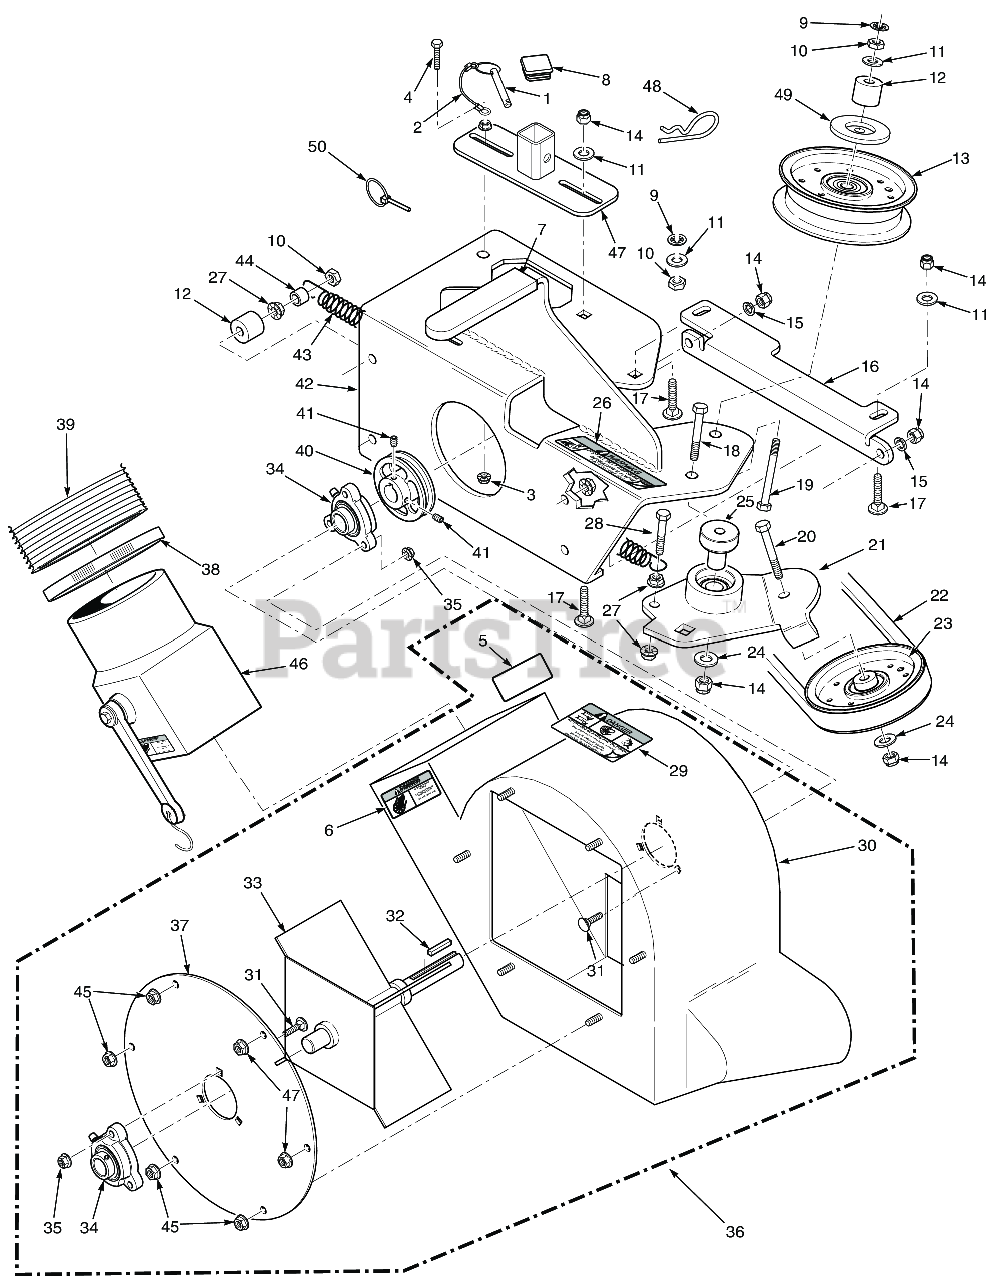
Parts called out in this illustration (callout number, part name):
1	Pin, Ring 1/2 x 2-1/4"
2	Lanyard, Deck Height Pin
3	NUT, 1/4-20 SERRATED FLANGE HEX HEAD
4	SERR. FLG. HEX HEAD CAPSCREW, 5/16-18 X 3/4
5	Decal, Blower
6	Decal, Rotating Blower
7	Grip, Deck Latch Lever
8	Cap, Square Vinyl
9	Nut, Push-On - 3/8" Dia.
10	Bolt, Hex Head 3/8-16 x 1" Ser. Flg.
11	Flatwasher, 3/8" Special (.391 x .938 x .105)
12	SPACER, J-PULL ROD
13	Pulley, Idler 3-1/2" Dia. - 52"
14	HEX NUT, ELASTIC STOP LOCK, 3/8-16
15	Lockwasher, 3/8" Spring, Kawasaki FX / FS
16	Plate, Catcher Mounting
17	Bolt, RDHD Carr. 3/8-16 x 1-1/2 (52" & 61")
18	Bolt, Hex Head 3/8-16 x 3" - 52"
19	Bolt, Hex Head 3/8-16 x 3-1/2" Full Thread
20	Bolt, Hex Head 3/8-16 x 1-3/4" (Kohler EFI)
21	Idler Arm Assembly - 52"
22	Belt, GC-SCZ-48V / STCII-48V
23	Pulley, 3-1/2" O.D., GC-STT 52"
24	Flatwasher, 3/8 (.391 x .938 x .105 HD) Grade 8
25	Pivot, Idler Long - 52"
26	Decal, Warning - Belt Cover
27	NUT, 3/8-16 SERRATED FLANGE HEX HEAD
28	Bolt, Hex Head 3/8-16 x 1-1/2" Grade 8 Black
29	Decal, Danger
30	Blower Housing Weldment w/Decals
31	Bolt, 5/16-18 x .75 RHSN Carriage
32	KEY 1/4 X 1/4 X 1 1/2"(FOR 1" CRANKSHAFT
33	Fan Weldment
34	Bearing Assembly
35	HEX NUT, ELASTIC STOP LOCK, 5/16-18
36	Blower Housing Assembly, GC-STT
37	COVER, BLOWER HOUSING
38	Clamp, 8-5/8" Max Dia. (61")
39	Hose, 8.00" Dia. x 68" Long
40	Pulley, 4-3/4" O.D. - 1" Bore
41	Setscrew, Hex Socket Knurl Cup Pt. 5/16 - 18 (nylock)
42	Frame, Blower Mount
43	Spring, Helper (61" Cutter Deck Only)
44	Spacer, Deck Assist
45	Nut, Serrated Flange 5/16-18 (Right Front Engine Mounting, Briggs and Kohler Only)
46	Adapter, Blower GC-STC,
47	Receiver Weldment, Mount Post - 52"
48	Hair Pin Cotter, .177" x 3-1/4"
49	Quick Pin, 5/16" Dia.
50	Quick Pin, 5/16" Dia.
